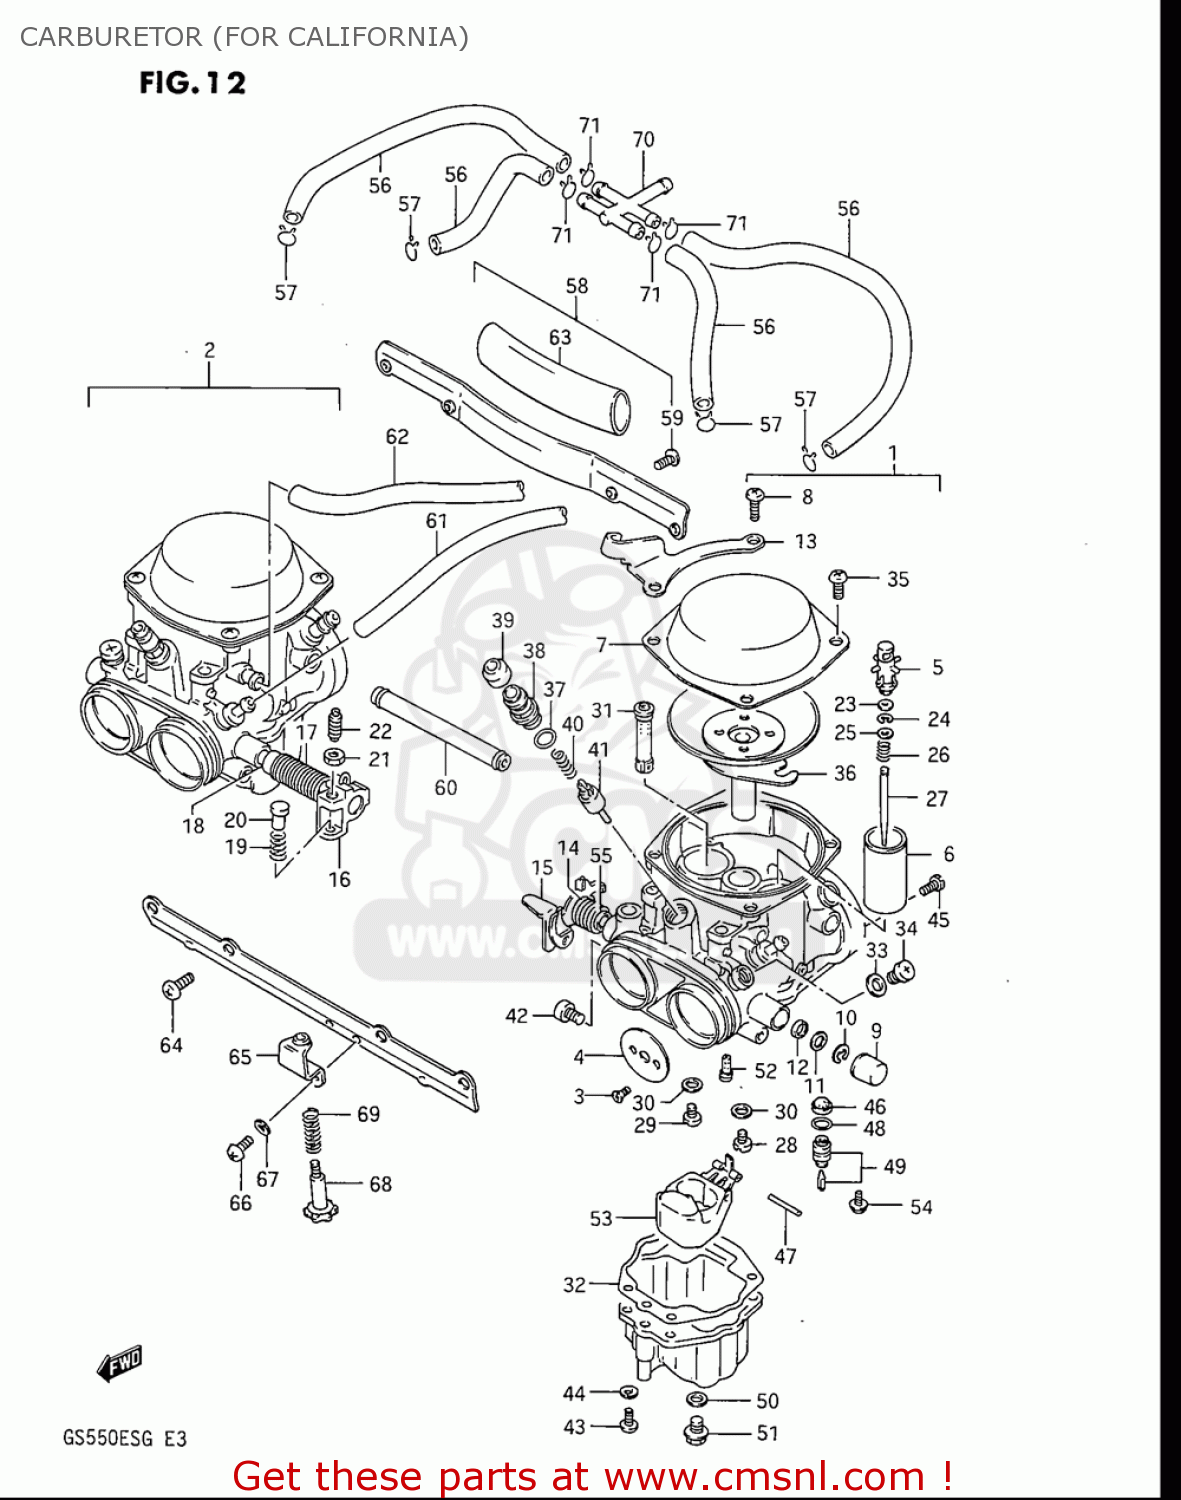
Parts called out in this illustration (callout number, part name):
3	SCREW
5	HOLDER,GUIDE
8	SCREW
9	CAP
10	E RING
11	GASKET,THROTTLE SHAFT (NAS)
12	SEAL
14	SPRING,THROTTLE SHAFT
17	SPRING
19	SPRING,THROTTLE SCREW
20	PIN,THROTTLE LEVER
21	NUT
22	SCREW
23	RING
24	CLIP
25	WASHER
26	SPRING
28	JET,MAIN(95)
29	JET,MAIN
30	WASHER
32	GASKET (NAS)
33	WASHER
34	SCREW
35	SCREW
36	DIAPHRAGM,CARBURETOR
37	O RING
38	HOLDER,GUIDE
39	CAP
40	SPRING
41	VALVE,STARTER
42	SCREW
43	SCREW 4X16
44	WASHER,LOCK
45	JET,PILOT(150)
46	FILTER
47	PIN,FLOAT
48	O RING,NEEDLE VALVE SEAT
49	VALVE ASSY,NEEDLE
50	GASKET (NAS)
51	PLUG,DRAIN
52	JET,PILOT(37.5)
53	FLOAT
54	SCREW
55	RING,THROTTLE SHAFT
57	CLIP
59	SCREW
60	PIPE,CARBURETOR
61	HOSE(4.5X8.5X600)
62	HOSE(7X11X600)
63	HOSE(16X19X100)
64	SCREW
66	SCREW
67	LOCK,WASHER
68	ADJUSTER
69	SPRING
71	CLIP
